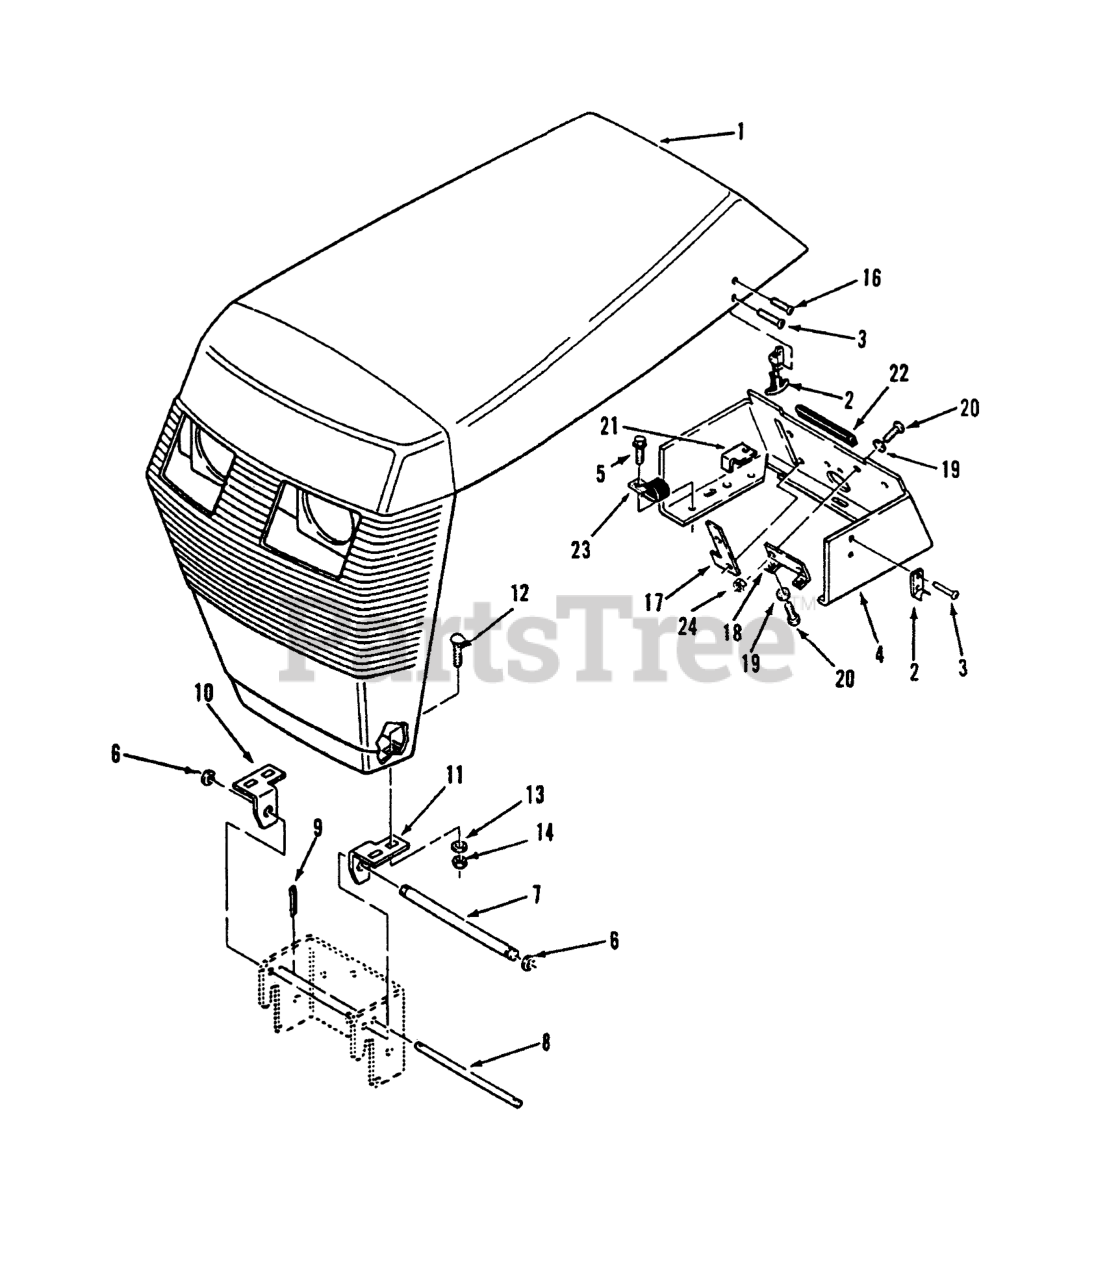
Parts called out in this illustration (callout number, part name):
1	Hood
2	LATCH-FLEX BLK ASS'Y
3	RIVET-POP
4	Console
5	SCREW
6	RING-RETAINING
7	ROD-GRILL PIVOT
8	ROD-HOOD STOP
9	Cotter Pin
10	BRACKET-GRILL, R H
11	BRACKET-GRILL, LH
12	SCREW-CARR
13	WASHER-FLAT
14	NUT-LOCK
16	POPRIVET 1/8X 1/8 BK
17	Washer
18	BRACKET
19	Washer-Lock
20	SCREW
21	STOP-PTO
22	EDGING-CONSOLE
23	J-CLIP
24	NUT-HEX
